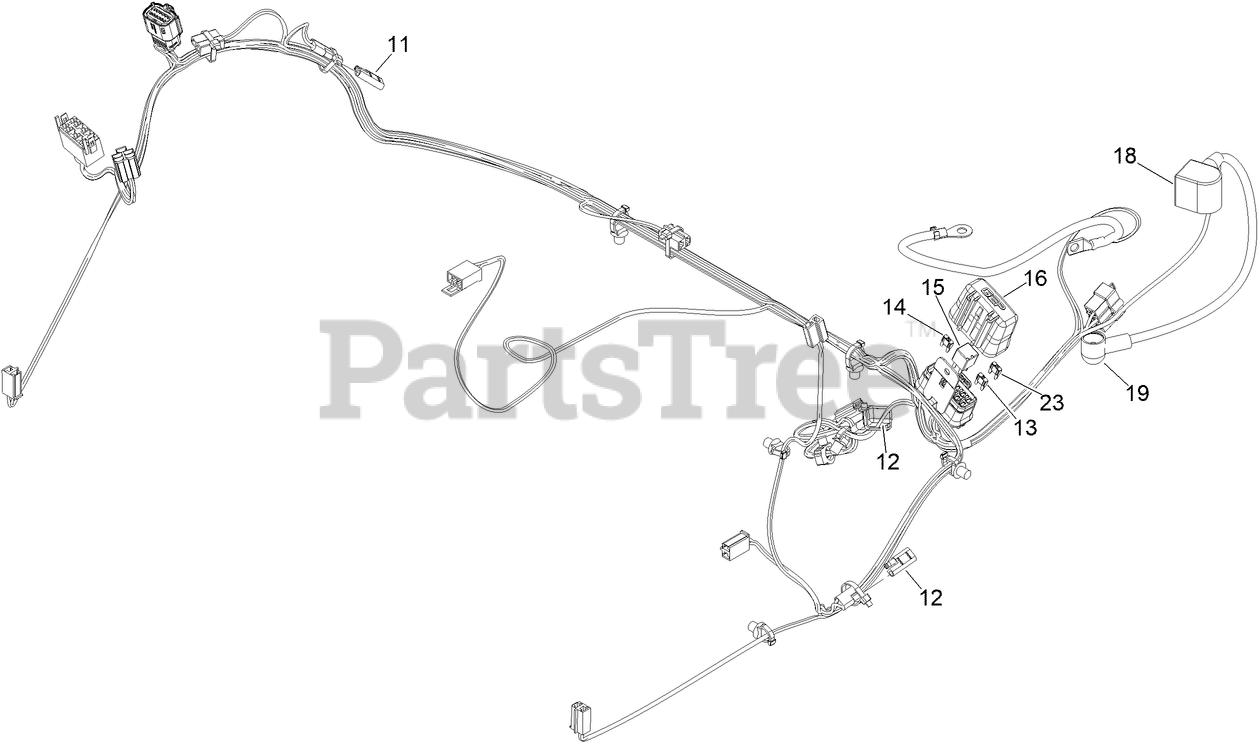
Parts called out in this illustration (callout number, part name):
11	CAP-PLUG
13	FUSE-MINI BLADE, 15 AMP
14	FUSE-MINI BLADE, 20 AMP
15	RELAY-MICRO
16	COVER-BLOCK, FUSE
18	INSULATOR-BATTERY
19	INSULATOR-SOLENOID
23	FUSE-MINI BLADE, 25 AMP
